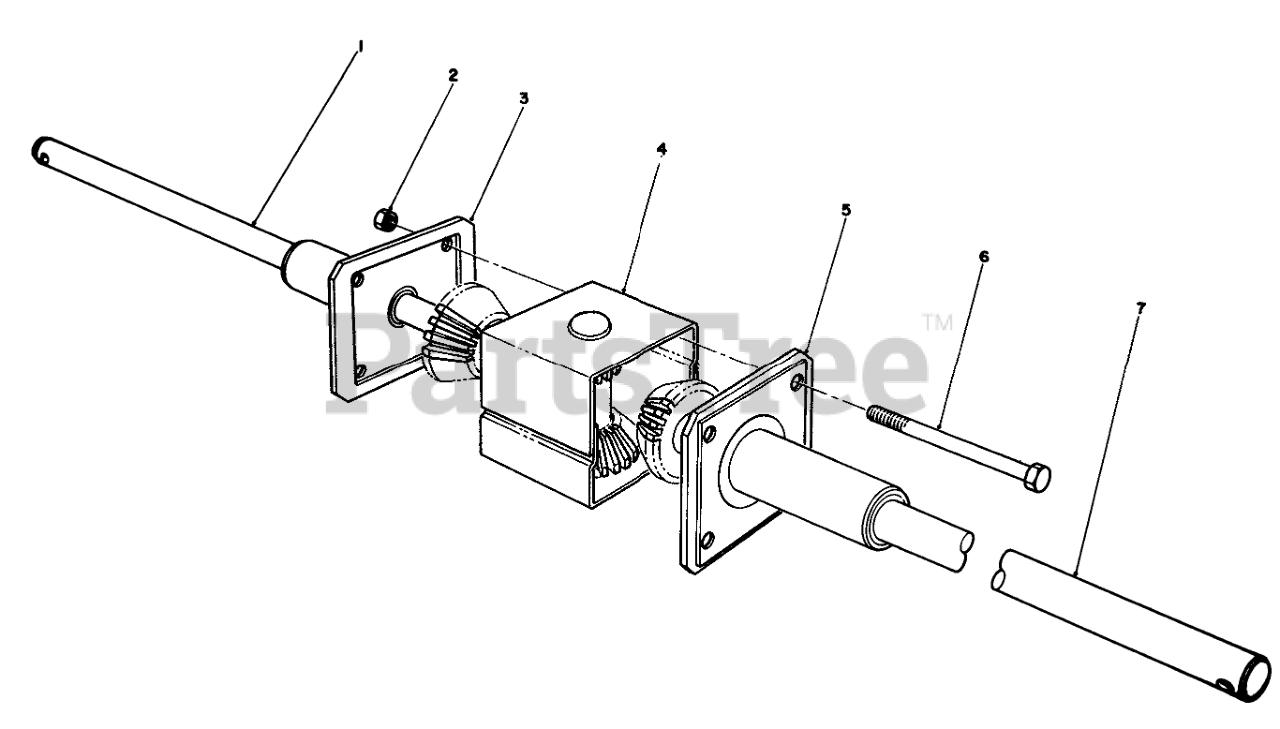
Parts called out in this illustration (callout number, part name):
2	NUT-LOCK, CONE
3	END CAP/BRG ASM
4	GEAR CASE ASM
5	END CAP &BEARING ASY
6	SCREW-HH
